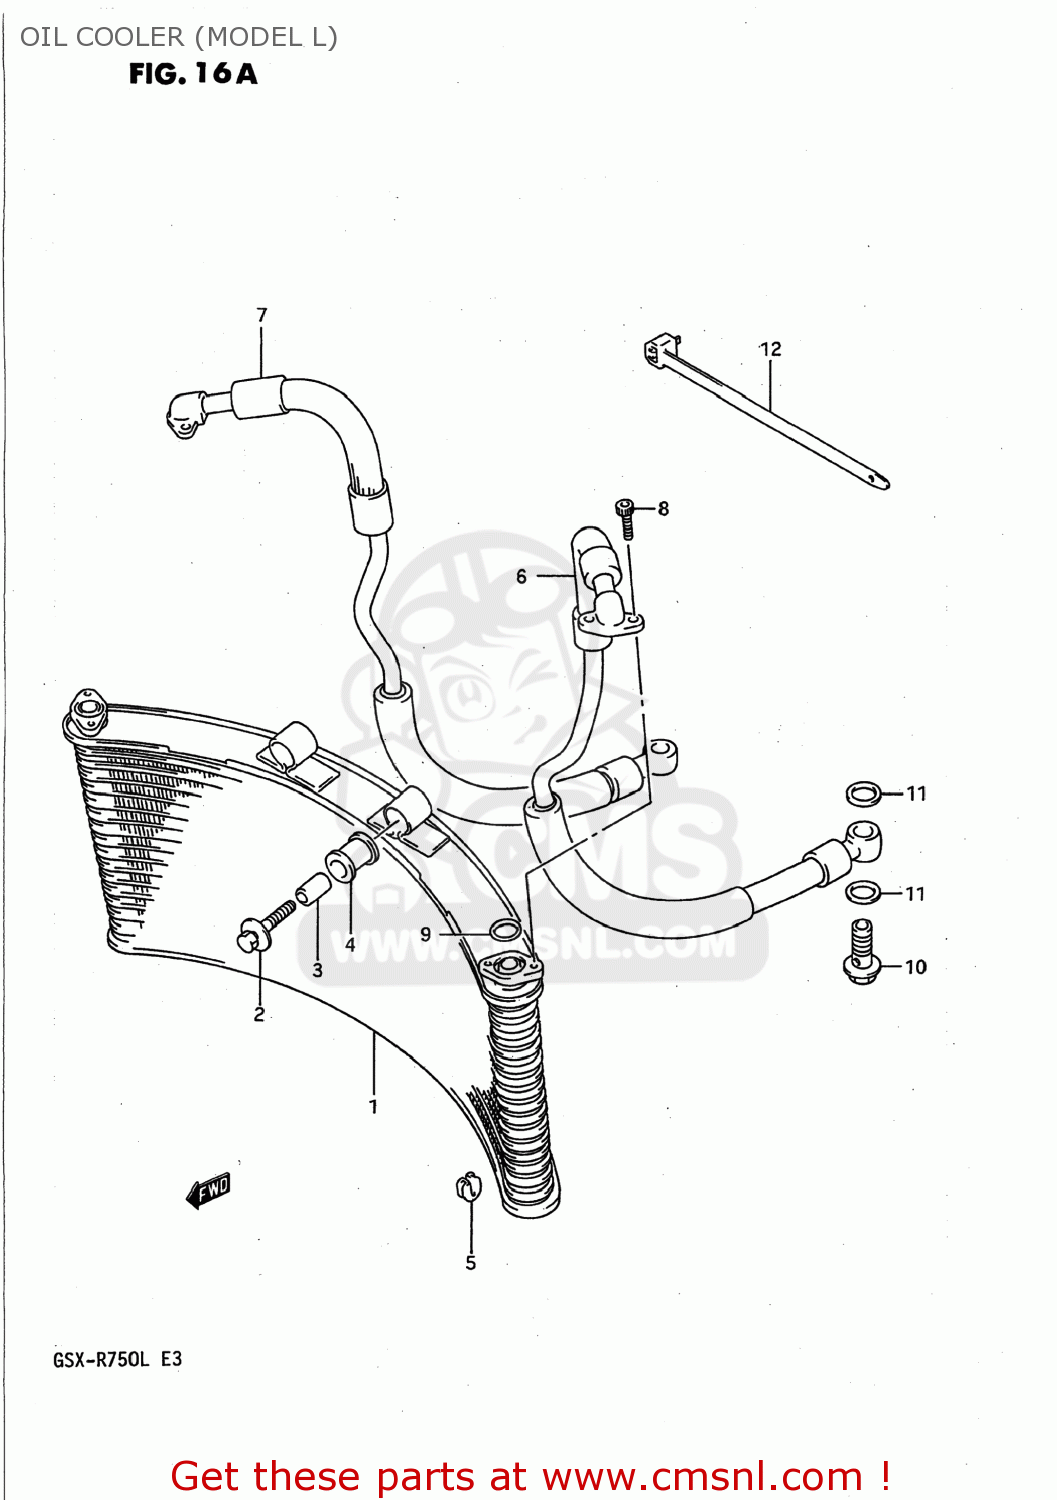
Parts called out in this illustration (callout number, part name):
1	COOLER ASSEMBLY,OIL
2	BOLT(8X40)
3	SPACER (8.8X12X24.5)
4	CUSHION,OIL COOLER NO.1
5	CUSHION,OIL COOLER NO.2
6	HOSE,OIL
7	HOSE,OIL
8	BOLT
9	O RING(D:2.4,ID:12.3)
10	BOLT UNION
11	GASKET(16X22X2) (NAS)
12	CLAMP
